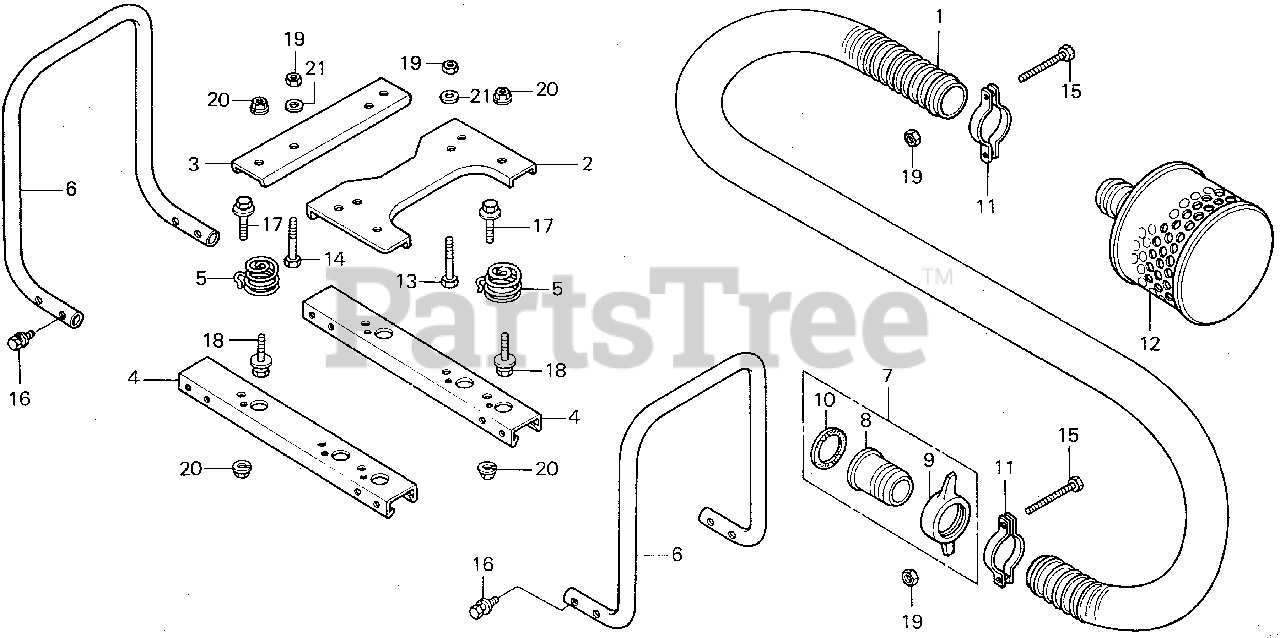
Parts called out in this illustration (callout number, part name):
1	HOSE, SUCTION (RUBBER)
1	HOSE, SUCTION (VINYL)
2	BRACKET A, MOUNTING
3	BRACKET B, MOUNTING
4	BED, FRAME
5	SPRING, MOUNT
6	HANDLE, CARRYING
12	STRAINER (NOT AVAILABLE)
13	BOLT, HEX. (8X25)
13	BOLT, HEX. (8X28)
14	BOLT, HEX. (8X35)
15	BOLT, HEX. (8X45)
16	BOLT-WASHER (8X20)
17	BOLT-WASHER (8X20)
18	BOLT-WASHER (8X25)
19	NUT, HEX. (8MM)
20	NUT, FLANGE (8MM)
21	WASHER, PLAIN (8MM)
